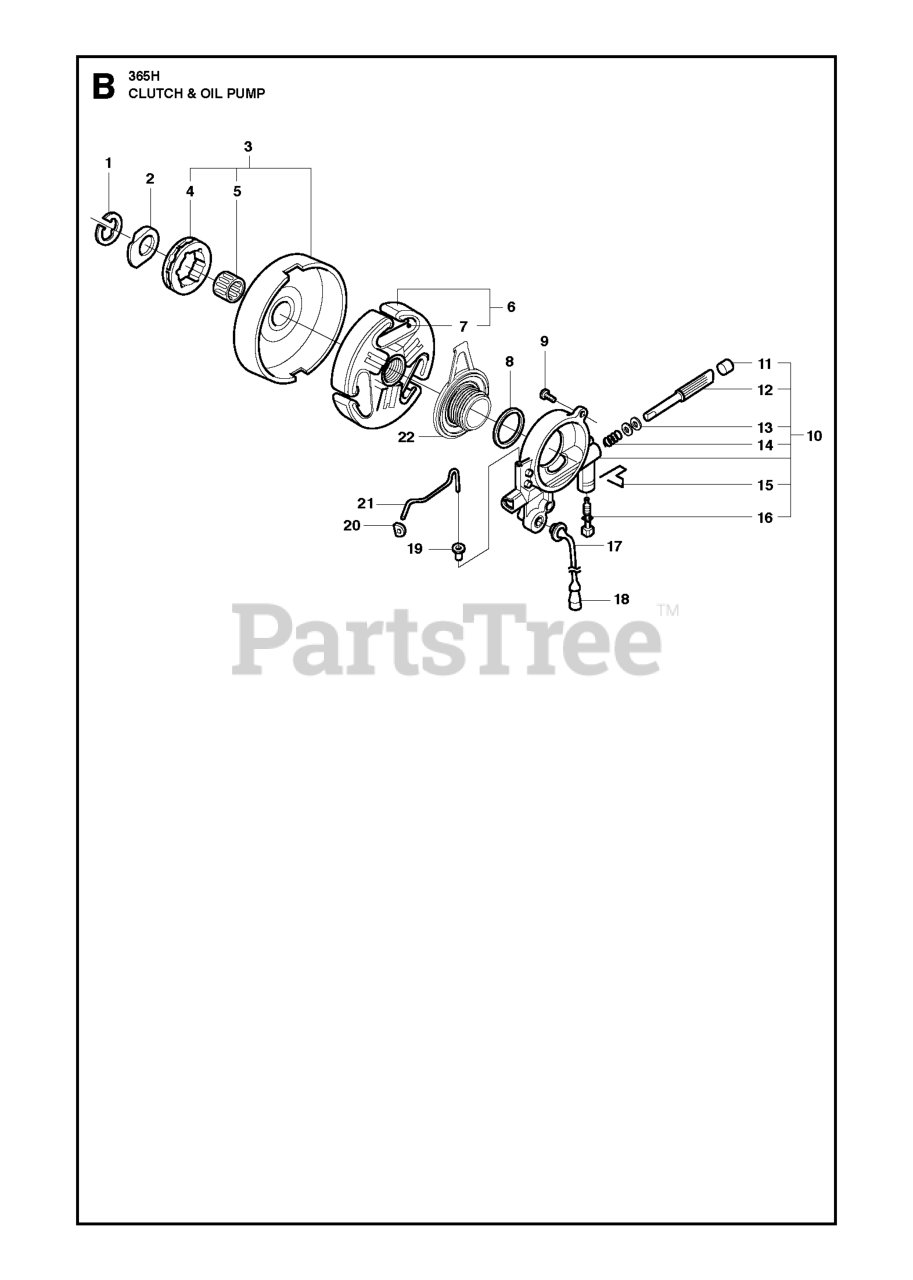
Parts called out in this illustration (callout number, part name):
1	RETAINING RING
3	CLUTCH DRUM
4	22273 Sprocket 3/8"x8T
4	68210 RIMSPROCKET
5	CLUTCH DRUM BEARING
6	CLUTCH
9	SCREW MC6S 5X16
10	OIL PUMP
12	PUMP PISTON
13	WASHER 6.1X9
15	SPRING CLIP
18	OIL SCREEN
22	OIL PUMP DRIVE
